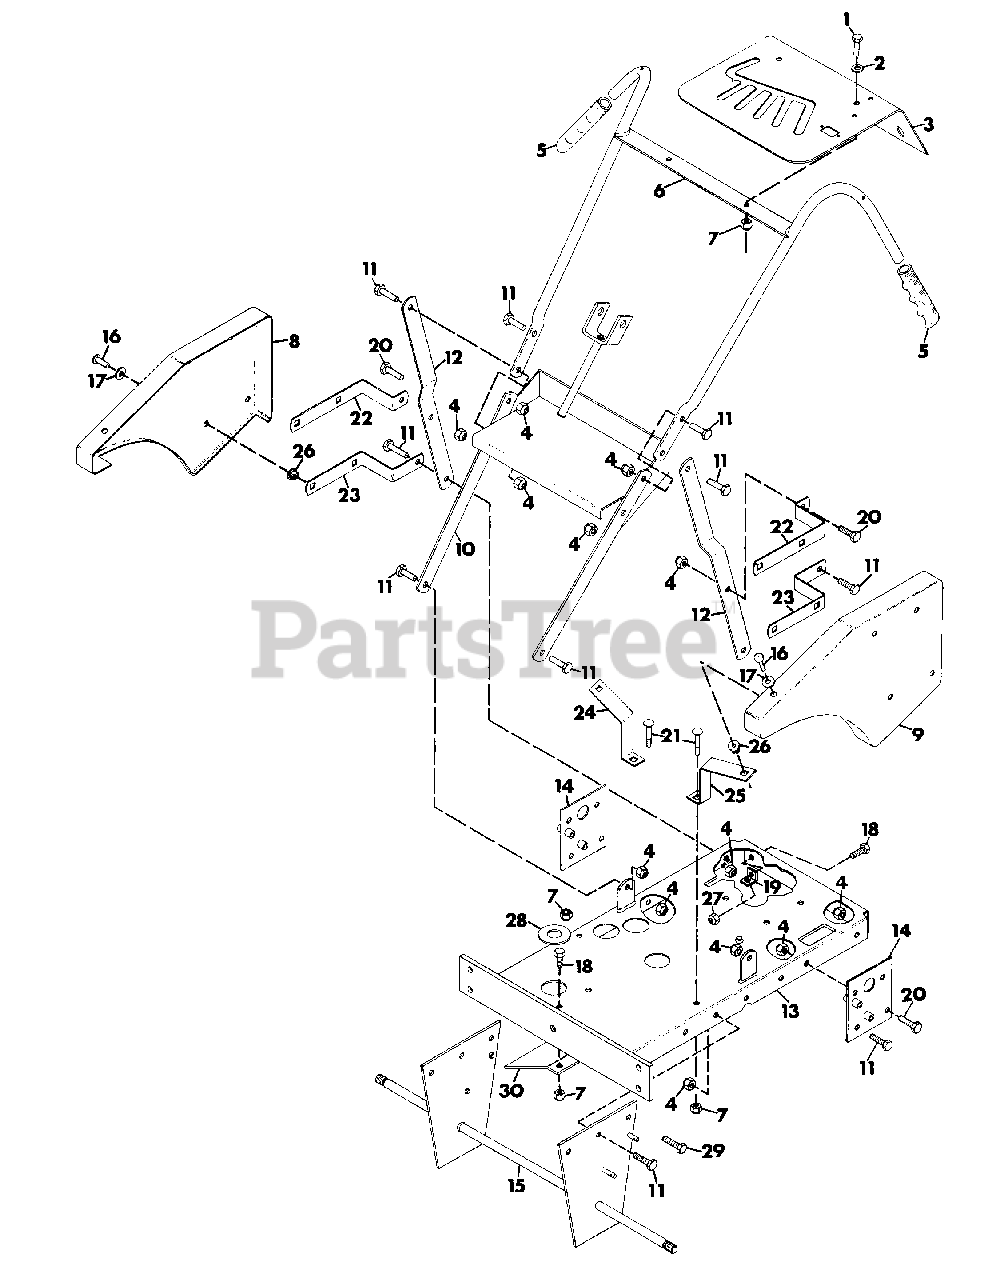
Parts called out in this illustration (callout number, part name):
1	BOLT, HEX 5/16-18X1.00
2	WASHER, FLAT .344X.688X.065
3	PLATE, INSTRUCTION
4	NUT, LOCK 3/8-16
5	GRIP, HAND
6	WELDMENT, HANDLEBAR
7	NUT, LOCK 5/16-18
8	GUARD, BELT R.H.
9	GUARD, BELT L.H.
10	WELDMENT, HANDLEBAR SUPPORT
11	BOLT, HEX 3/8-16X1.25
12	BRACE, HANDLEBAR SUPPORT
13	WELDMENT, FRAME
14	WELDMENT, BEARING SUPPORT
15	WELDMENT, AXLE
16	SCREW, MACHINE 1/4-20X.625 RD HD
17	WASHER, FLAT .281X.625X.065
18	BOLT, HEX 5/16-18X.625
19	TAB, SPRING
20	BOLT, HEX 3/8-16X1.00
21	BOLT, HEX 5/16-18X.75
22	BRACKET, TOP
23	BRACKET, BOTTOM
24	SUPPORT, FRONT R.H.
25	SUPPORT, FRONT L.H.
26	GROMMET, PLASTIC
27	NUT, LOCK 5/16-18
28	WASHER, FLAT 1.38X3.0X.165
30	BRACE
NS	DECAL, AMERICA
